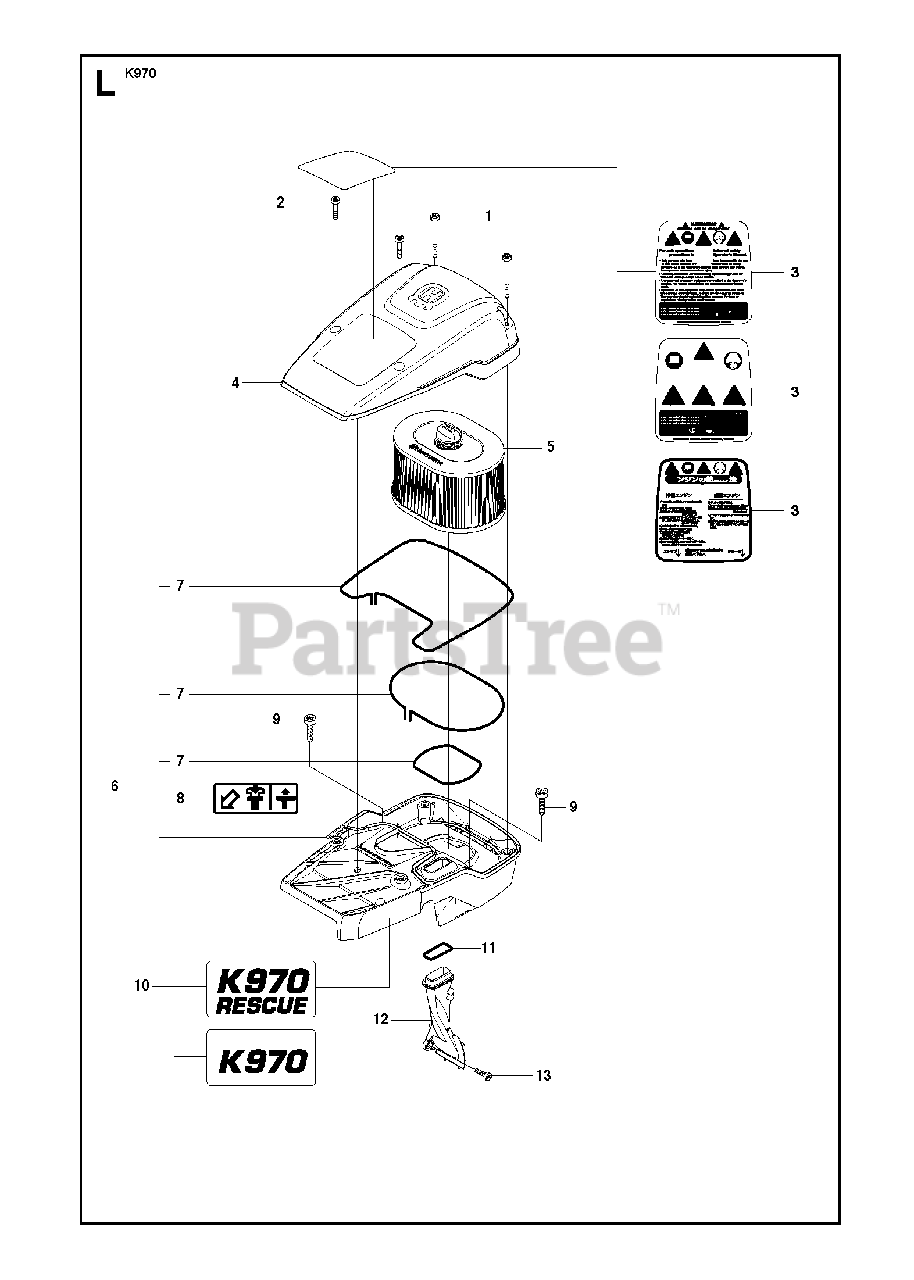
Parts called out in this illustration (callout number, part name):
1	SCREW ITXSCM
2	SCREW ITXSCM
3	DECAL
4	FILTER COVER
5	AIR FILTER
6	CYLINDER COVER ASSY
9	SCREW ITXSCM
12	AIR NOZZLE
13	SCREW ITXSCM
